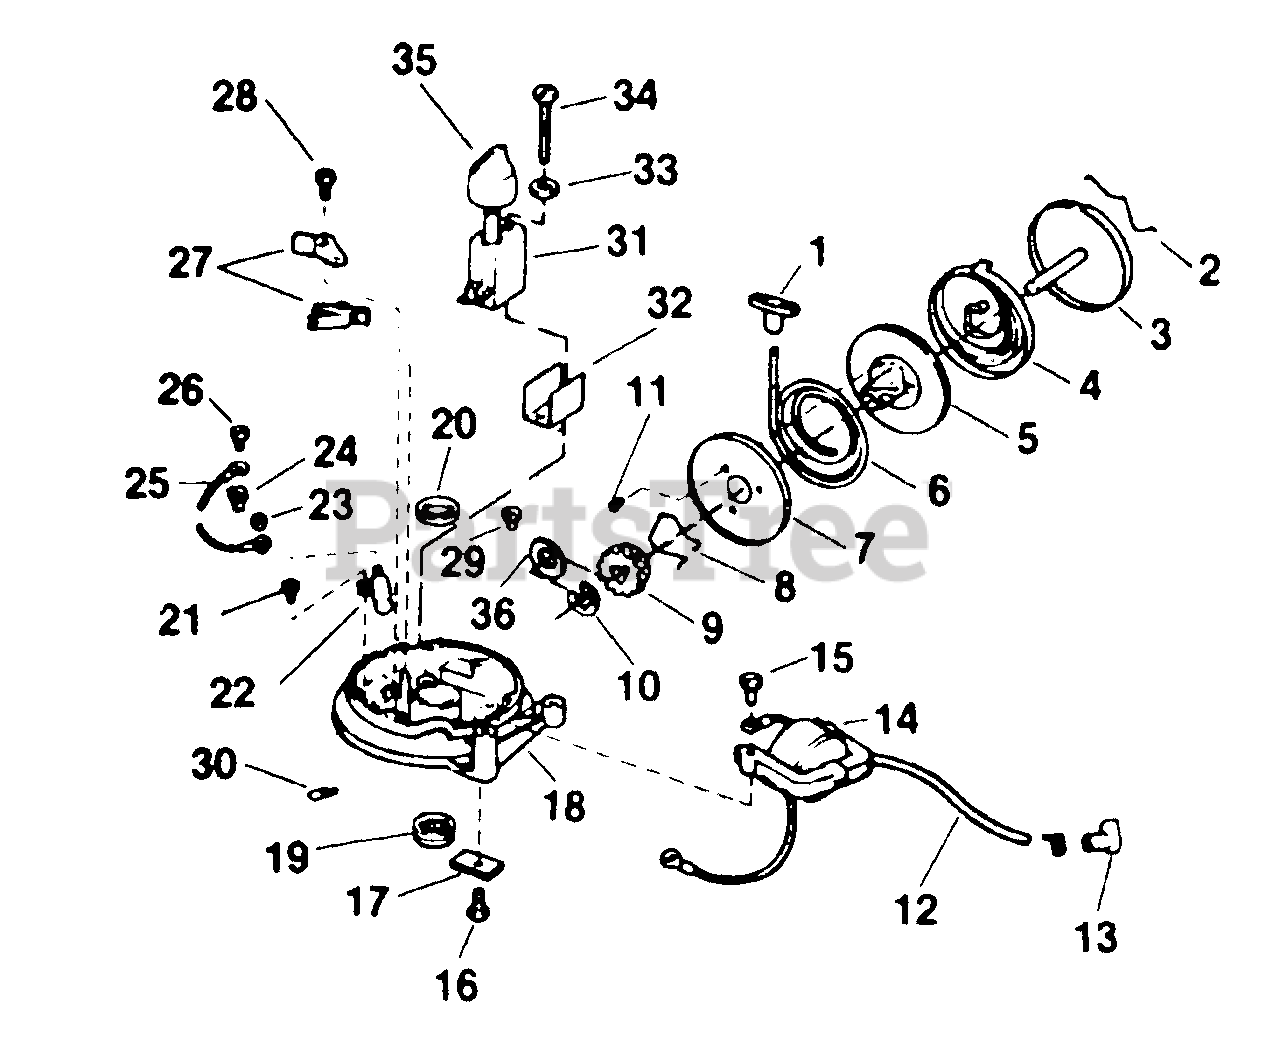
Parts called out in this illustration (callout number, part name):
1	Handle-Starter
2	Spring-Starter Rope Retainer
3	Spring-Cup Pin Assy.
4	Spring-Starter
5	Pulley-Starter
6	Rope-Starter
7	Plate-Starter Pulley
8	Spring-Starter Pinion
9	Pinion-Starter
10	Retainer-Push-On
11	Scr.-Threaded Cutting Starter
12	High Tension Lead Assy.
13	Cover & Terminal Assy.
14	Coil & Lamination Assy.
15	Scr.-Lamination Mtg.
16	Scr.-Starter Attach.
17	Clamp-Starter Pin
18	Arm. Pl., Brg. & Oil Seal Assy.
19	Bearing
20	Oil Seal
21	Oil Seal
22	Cond. & Nut Assy.
24	Grommet-Nylon
25	Terminal & Lead Assy.
26	Screw-Shut-Off Switch
27	Brkr. Base & Arm Assy.
28	Screw-Breaker Base
29	Grommet
31	Shorting Switch
32	Insulator
